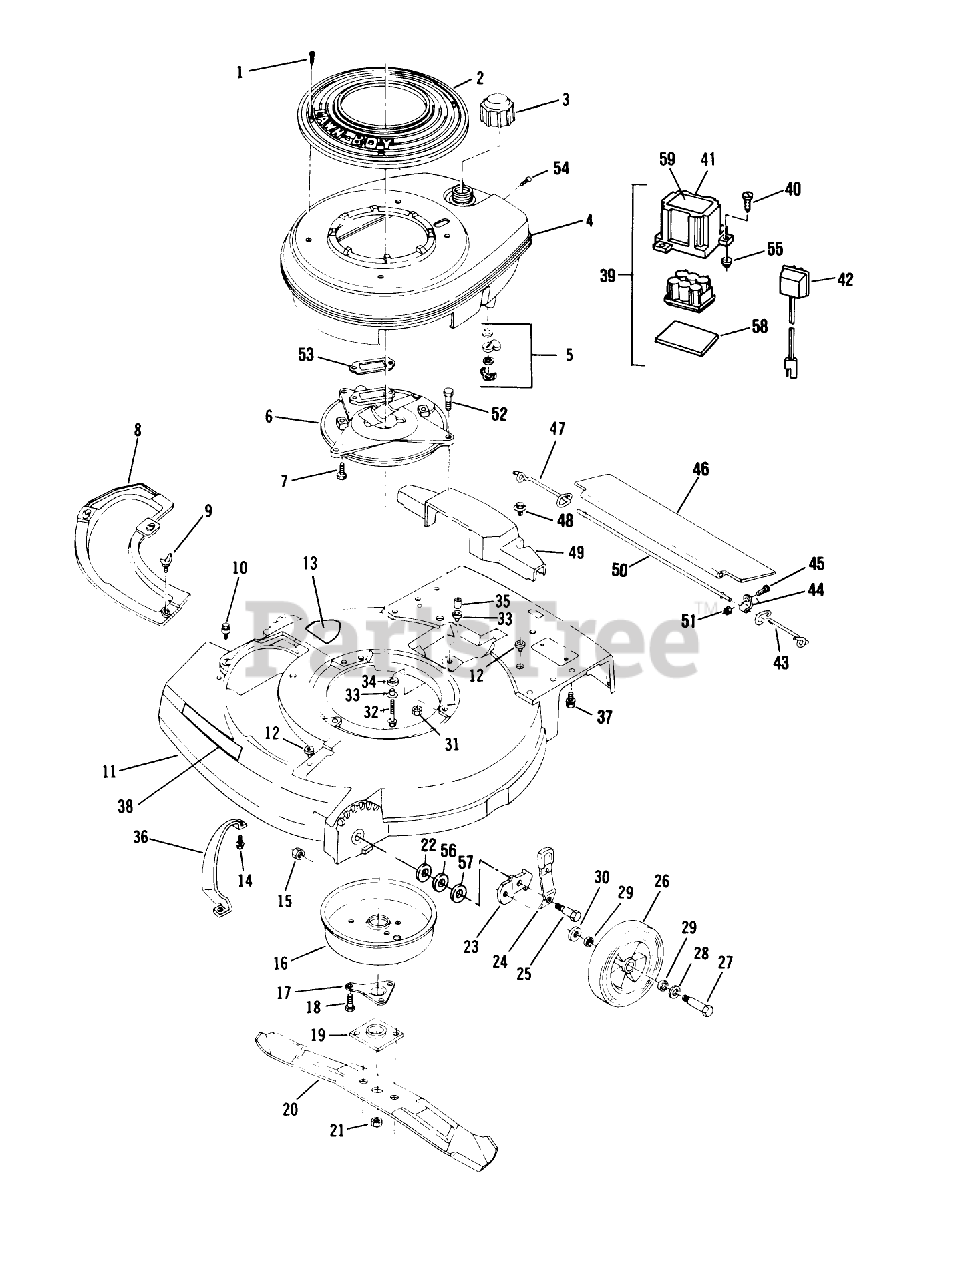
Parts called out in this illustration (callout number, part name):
1	SCREW - SELF TAPPING
3	FUEL CAP & INSERT
5	SHUT OFF VALVE KIT
7	SCREW V
9	WING SCREW LAWRE
15	LOCKNUT
16	MUFFLER COVER F
17	SUPPORT F
18	SCREW
19	PLATE AND COLLAR ASM
21	NUT-BLADE
22	WASHER
24	SPRING ARM ASM
25	BOLT
26	WHEEL & TIRE KIT
27	BOLT WHEEL
28	SPACER
29	WASHER
30	WASHER WROUGHT
31	NUT-LOCK F
33	SPACER ECK PRES
34	GROMMET
35	SPACER
36	BAR-TOE
37	SCREW
40	SCREW - SELF TAPPING
43	SPRIG T/SHLD ASOC
44	CLAMP ROD KMC
46	SHIELD
47	SPRING;TRAILING SHIELD RH
48	SCREW SEMS TRM HEX HD
50	ROD 21" ADVANCE
51	LOCKNUT E
52	SCREW-HH
54	SCREW S
55	NUT-CLIP
56	WASHER
57	WASHER
58	PAD-BATTERY
